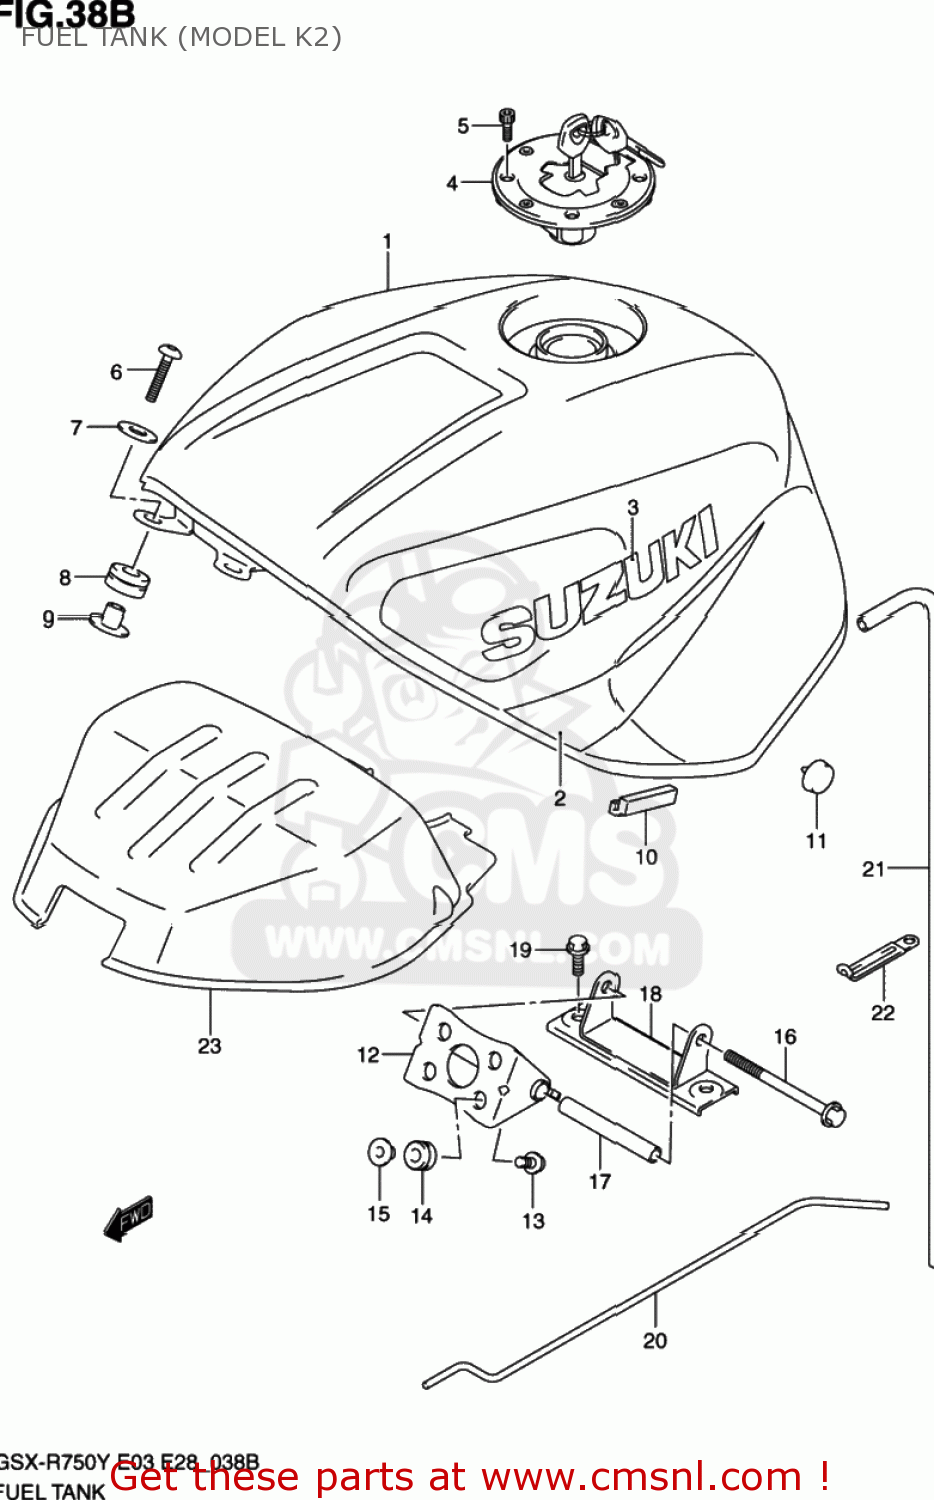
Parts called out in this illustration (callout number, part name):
1	TANK ASSY,FUEL
2	TAPE SET,FUEL TANK
3	EMBLEM,FUEL TANK
4	CAP SET,FUEL TANK
5	BOLT(5X20)
6	SCREW(6X25)
7	WASHER(6.5X22X1.6)
8	CUSHION,FUEL TANK FR
9	SPACER,FUEL TANK FR
10	CUSHION,FUEL TANK SIDE
11	CUSHION,FUEL TANK SIDE NO.2
12	BRACKET,FUEL TANK NO.1
13	BOLT(6X20)
14	CUSHION
15	WASHER
16	BOLT
17	SPACER,FUEL TANK RR
18	BRACKET,FUEL TANK NO.2
19	BOLT
20	STAY,FUEL TANK
21	HOSE,FUEL TANK WATER DRAIN
22	CLAMP(L:65)
23	SHIELD,FUEL TANK HEAT
